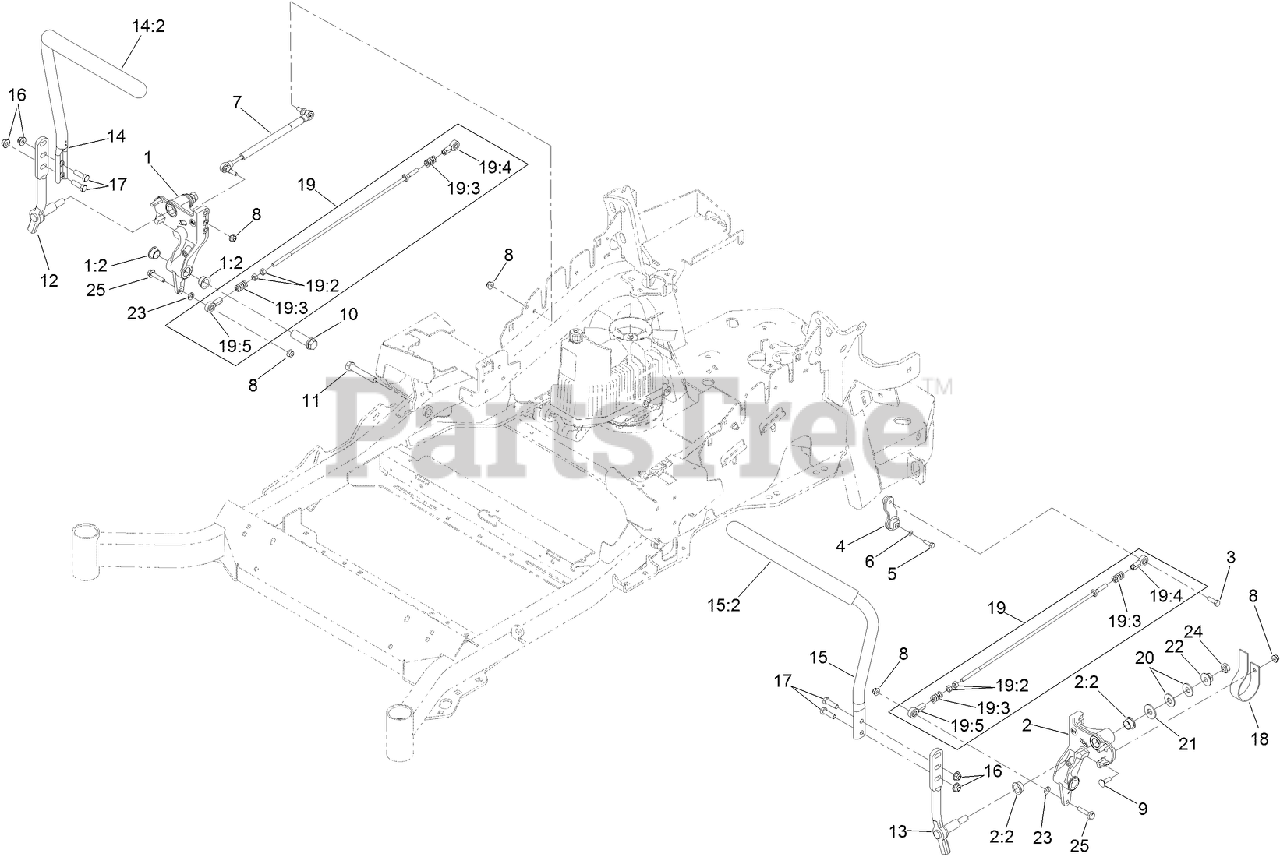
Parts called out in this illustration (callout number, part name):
1	RH MOTION CONTROL AND BUSHING ASM
1:2	BUSHING-FLANGE
2	LH MOTION CONTROL AND BUSHING ASM
2:2	BUSHING-FLANGE
3	SCREW-HH, THREAD LOCKING
4	ARM-CONTROL, PUMP
5	SCREW-HH
6	WASHER-SPRING
7	DAMPER-CONTROL, MOTION
8	NUT-HF, NI
9	BOLT-CARR
10	HUB-THREADED
11	SCREW-HH
12	LEVER-CONTROL MOTION, RH
13	LEVER-CONTROL MOTION, LH
14	RH STEERING HANDLE ASM
14:2	GRIP-CONTROL, LEVER
15	LH STEERING HANDLE ASM
15:2	GRIP-CONTROL, LEVER
16	NUT-HF, NI
17	SCREW-HH
18	SPRING-LEAF
19	FRONT PUMP LINKAGE ASM
19:2	NUT-HEX
19:3	SPRING-COMPRESSION
19:4	BALLJOINT-LH
19:5	BALLJOINT-RH
20	WASHER-SPRING
21	WASHER-FLAT
22	NUT-HF
23	WASHER-PLAIN
24	NUT-JAM
25	SCREW-HHF
